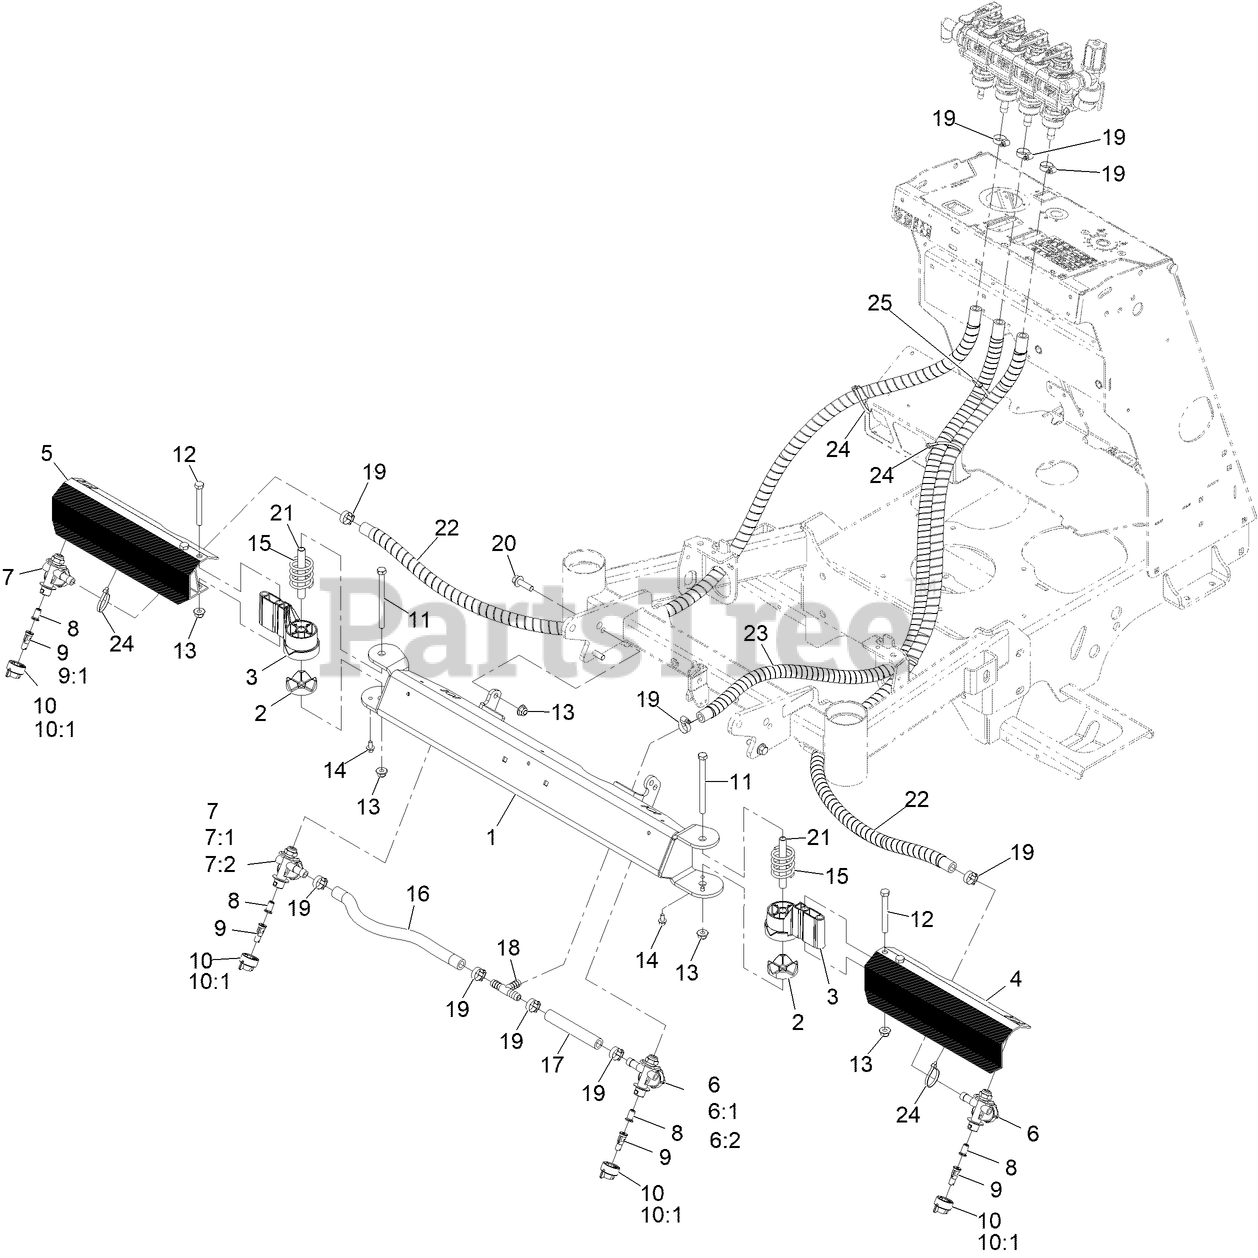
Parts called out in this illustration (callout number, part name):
1	BOOM-CENTER, WELDED
2	BOOM-PIVOT
3	HINGE-BOOM
4	BOOM-WING, LH
5	BOOM-WING, RH
6	BODY-NOZZLE, LEFT
6:1	CAP-DIAPHRAM
6:2	DIAPHRAGM FOR CHECK VALVE
7	BODY-NOZZLE, RIGHT
7:1	CAP-SPRAYER NOZZLE
7:2	DIAPHRAGM-SPRAYER NOZZLE
8	STRAINER-NOZZLE, 50M 5PSI
9	NOZZLE-SPRAYER
9	TIP-SPRAY, 015
9	TIP-SPRAY, 02
9	TIP-SPRAY, 025
9	TIP-SPRAY, 03
9	TIP-SPRAY, 04
9	TIP-SPRAY, 05
9	TIP-SPRAY, 06
9	TIP-SPRAY, XRC11020
9:1	SEAT-GASKET
10	CAP-NOZZLE
10:1	SEAT-GASKET
11	SCREW-HH
12	SCREW-HH
13	Nut-Hex Flange
14	SCREW-HWH
15	SPRING-COMPRESSION
16	Hose-Spray
17	Hose-Spray
18	FITTING-TEE
19	CLAMP-HOSE
20	SCREW-HHF
21	SPACER-BOOM, PIVOT
22	HOSE-SPRAY, WRAPPED
23	HOSE-SPRAY, WRAPPED
24	TIE-CABLE
25	CLIP-TIE
